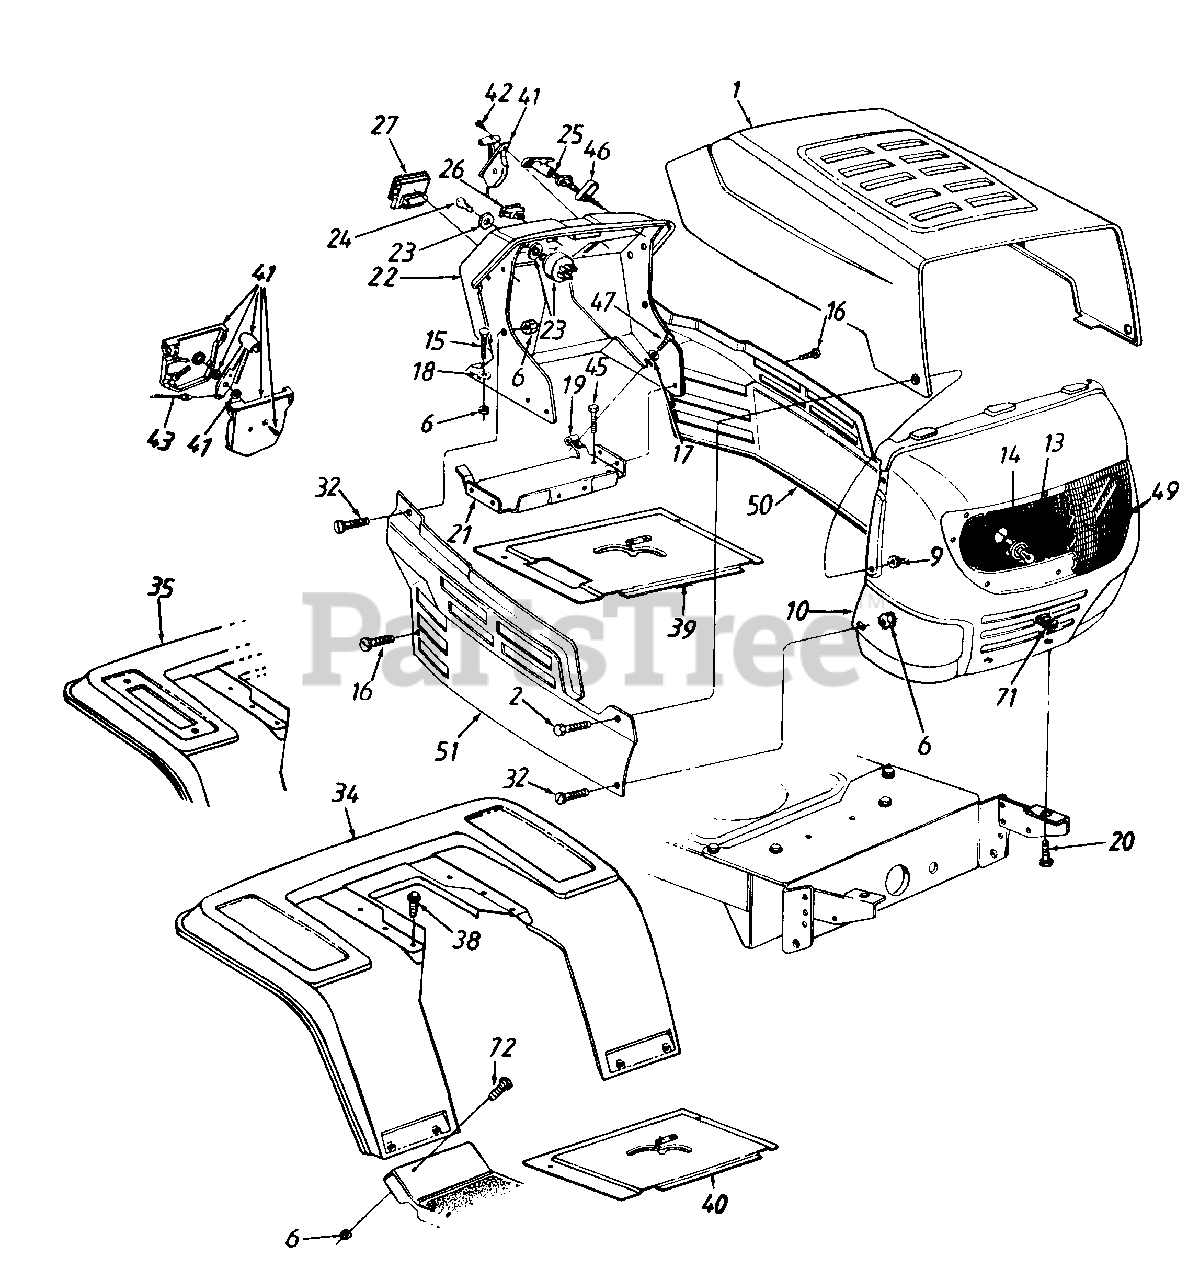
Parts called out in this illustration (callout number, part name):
6	Hex Sems Nut 1/4-20 Thd.
9	Flange L-Nut 1/4-20 Thd.
13	Lamp
14	Socket
15	Carriage Bolt 1/4-20 x .75" Lg.
16	Hex Wash. Hd. TT-Tap Scr. 1/4-20 x .5" Lg.
17	Fl-Wash. .281" I.D. x .73" O.D.
18	Bolt Retainer 1/4" I.D.
19	Speed Nut 1/4-20 Thd.
20	Hex Bolt 5/16-18 x .75" Lg.
23	Ignition Switch
24	Ignition Key
25	Choke Control
26	Light Switch
27	Ammeter
32	Pan Hd. Scr. 1/4-20 x .75" Lg
41	Throttle Box Ass'y
42	Truss Mach. AB-Tap Scr #10 x 5" Lg.
43	Throttle Control Wire
45	Hex Wash Hd. B-Tap Scr 5/16-18 x .5" Lg
46	Choke Retainer
47	Hex TT-Tap Scr. 1/4-20 x 75" Lg.
49	Lens - Sty 3
72	Truss Mach. Scr. 1/4-20 x .5" Lg.
